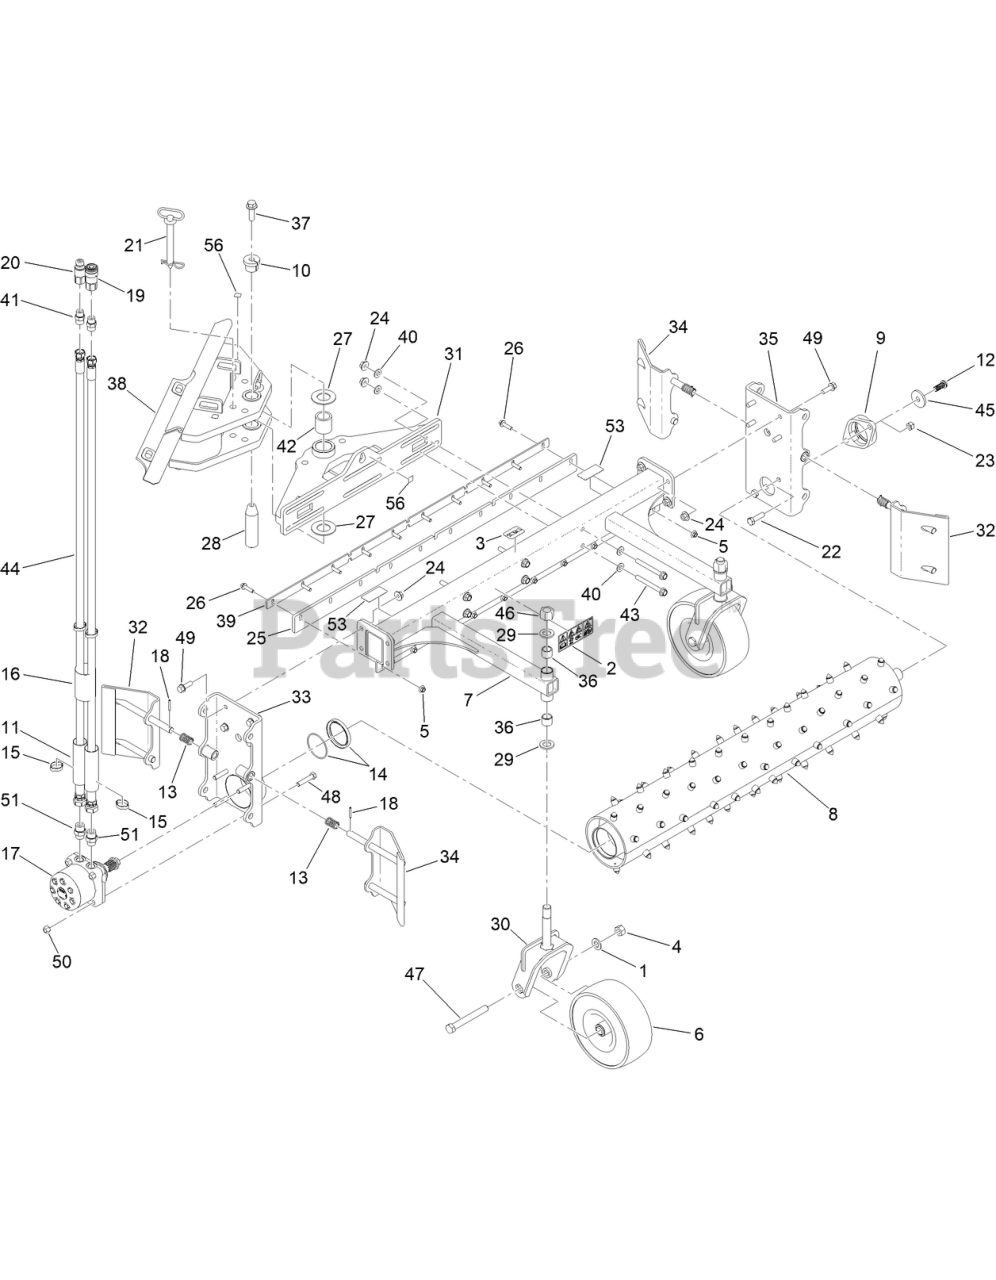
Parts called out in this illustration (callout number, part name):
1	WASHER-FLAT
2	DECAL-DANGER
4	NUT-LOCK
5	NUT-HF
7	TOP RAKE
8	RAKE DRUM
9	FLANGE BEARING
10	TAPERED INSERT
11	ABRASION SLEEVE
12	SCREW-HSBH
13	SPRING
16	ABRASION SLEEVE
18	PIN-ROLL
19	COUPLER-FACE, FLUSH
20	NIPPLE-FACE, FLUSH
22	BOLT HEX
23	NUT, M14 X 2.00-6H, TOPLK, CL 10, CZN
24	NUT-LOCK, FLANGE
25	MUD FLAP
26	SCREW-HHF
27	WASHER-FLAT
28	TAPERED PIN
29	WASHER
30	CASTER
31	RAKE SLIDE
32	RAKE WING
33	MOTOR MOUNT
34	RAKE WING
35	BEARING MOUNT
36	BUSHING-SLEEVE
38	RAKE PIVOT
39	FLAP MOUNT
40	WASHER-THRUST
41	FITTING-STRAIGHT
42	BEARING
43	SCREW-HHF
44	HOSE ASM
45	WASHER
47	BOLT-ADJUSTMENT
48	SCREW-HH
49	HFCS,1/2-13X1-1/2,WHIZLOCK,GR5 CZ
50	NUT,1/2-13,TOP L/N,GRB,CADWAX,YZN
51	FITTING-STRAIGHT
53	DECAL-DANGER, ENTANGLEMENT
56	DECAL-POINT, LIFT
